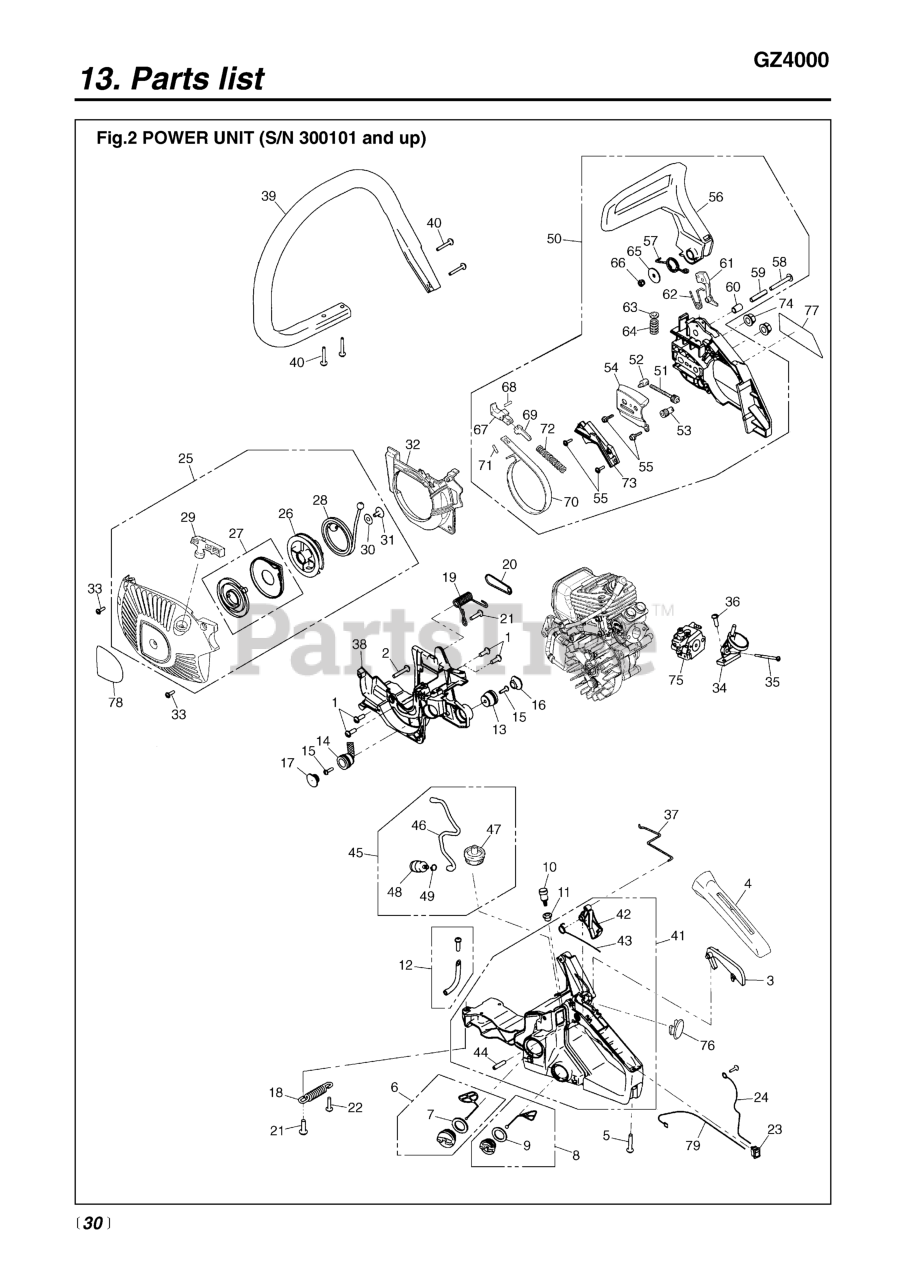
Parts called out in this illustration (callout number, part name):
1	SCREW (REPLACES 2616-24320)
2	SCREW
3	ARM (REPLACES 3356-33352)
4	COVER
5	SCREW
6	CAP ASSEMBLY
7	GASKET
8	CAP ASSEMBLY
9	GASKET
10	BREATHER ASSEMBLY
11	GROMMET
12	PIPE COMPLETE
13	DAMPER (RPLS 2670-35110)
14	DAMPER COMPLETE
15	SCREW
16	CAP
17	CAP
18	SPRING, FRONT
19	SPRING, REAR
20	PLATE
21	SCREW (RPLS. 2671-32110)
22	SCREW (REPLACES 2616-24320)
23	SWITCH ASSEMBLY
24	CORD, SWITCH
25	STARTER ASSY
26	REEL
27	SPRING
29	KNOB (RPLS -75420)
30	WASHER (USE 181741)
31	SCREW (RPLS. 2671-32110)
32	COVER, FAN
33	SCREW
34	MANIFOLD
35	BOLT
36	SCREW
37	ROD
38	CASE, ENGINE
39	HANDLE
40	SCREW
41	HANDLE, RIGHT ASSEMBLY
42	LEVER, THROTTLE
43	SPRING
45	PIPE ASSEMBLY
46	PIPE, FUEL
48	5500-85400 (RRLS. 1750-85300)
49	CLIP (REPLACES 2841-31280)
50	BRAKE ASSY
51	SCREW
52	NUT
53	GEAR
54	PLATE, GUIDE
55	SCREW
56	GUARD, FRONT
57	SPRING, RETURN
60	SPACER (RPLS -54210)
61	WEIGHT
63	PLATE, STOPPER
65	WASHER (RPLS -75410)
66	NUT (B)
67	LEVER, BRAKE COMPLETE
69	ARM, SLIDE(RPLS 2670-54410)
70	BAND, BRAKE
71	PIN
72	SPRING, BRAKE (RPLS. 50030121)
74	NUT
75	CARBURETOR-ASSY
76	CAP
